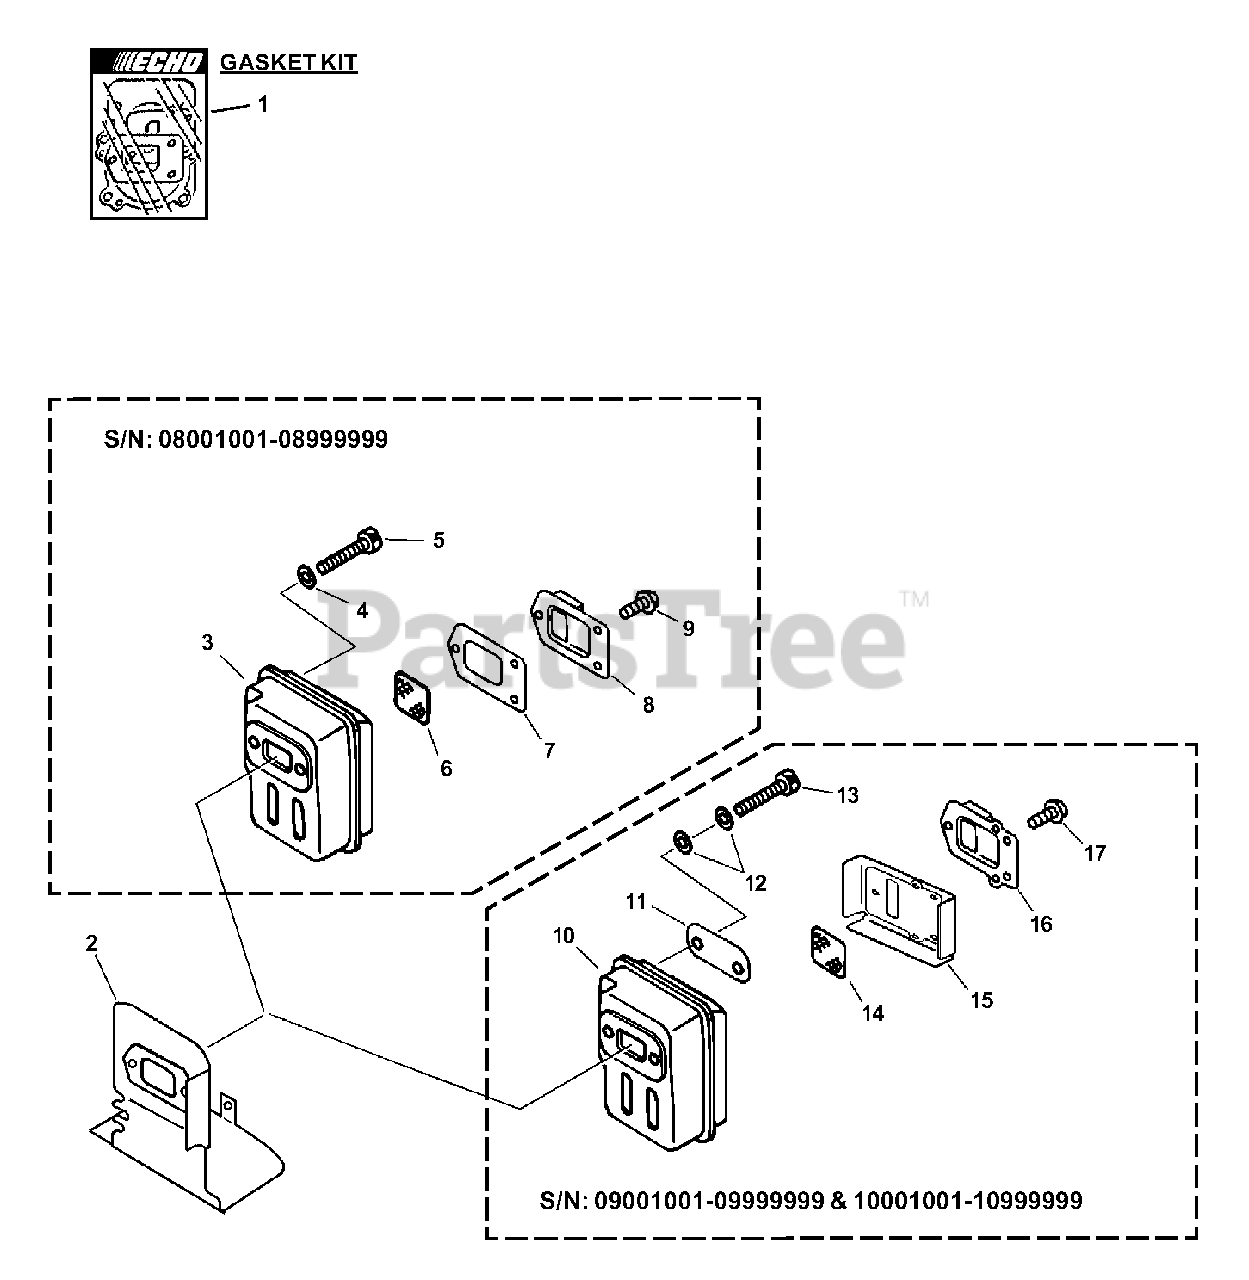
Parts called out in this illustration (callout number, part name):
1	GASKET KIT
2	SHIELD, EXHAUST
4	WASHER, FLAT 5.5×10×0.8
5	BOLT 5×55
6	SCREEN, SPARK ARRESTER
7	GASKET, EXHAUST
8	GUIDE, EXHAUST
9	SCREW 4×10
10	MUFFLER
11	PLATE, EYE
12	CONICAL WASHER
13	BOLT 5×55
14	SCREEN, SPARK ARRESTER
15	GASKET, EXHAUST
16	GUIDE, EXHAUST
17	SCREW 4×12
